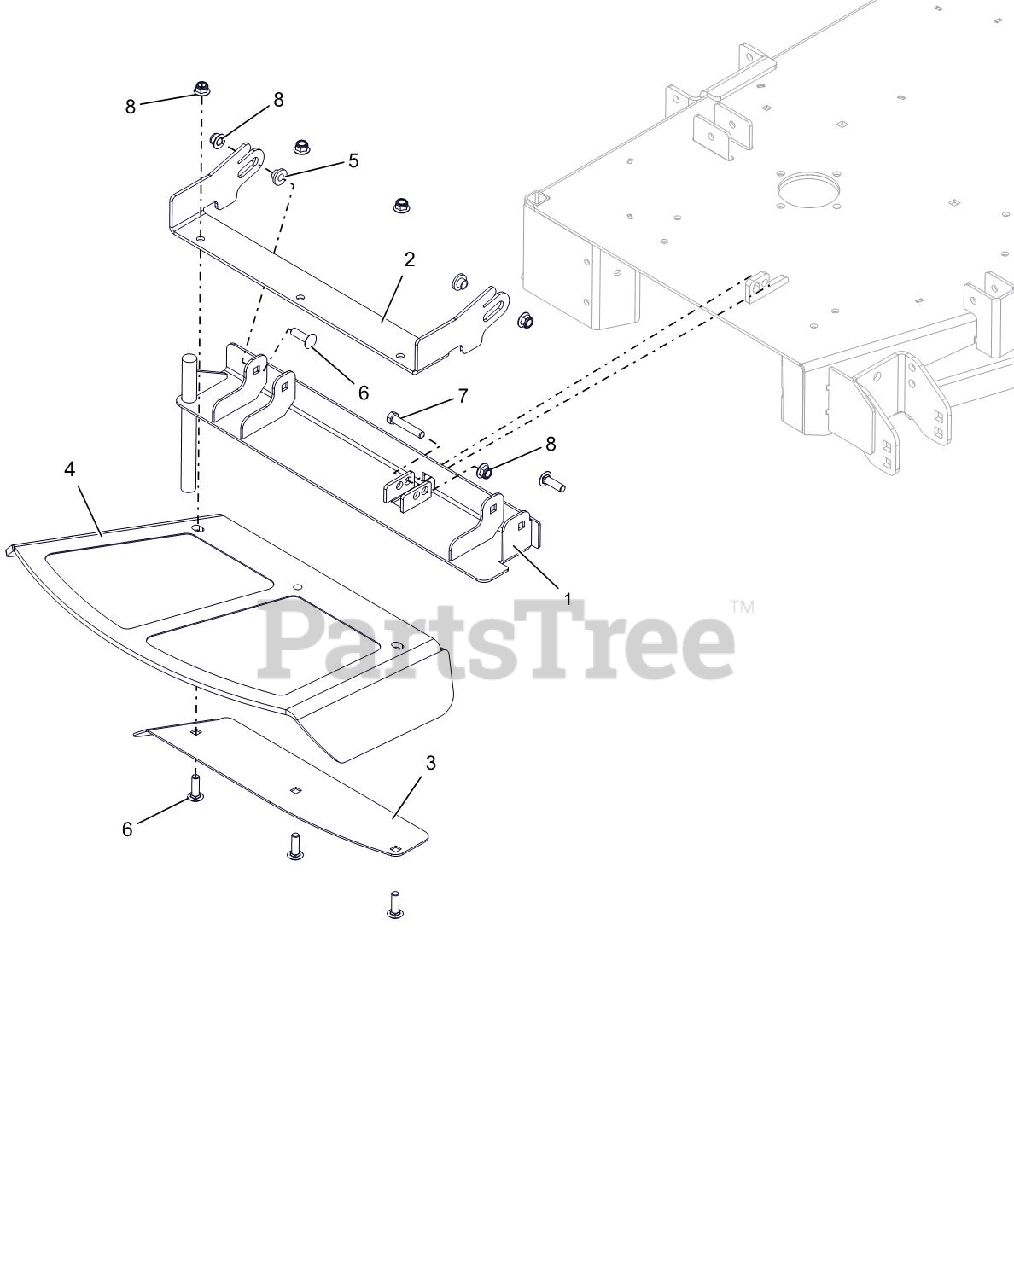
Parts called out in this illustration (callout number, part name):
1	48-60 DISCH CHT MTG WMT W/SAFE
2	48-60" CHUTE MTG BRKT - RED
3	48-60 DISCH CHUTE CLMP PLT-RED
4	CHUTE,48-60" FRMD RUBBER DISCH
5	BSHG-FLG .385X.500X.875X.406
6	@BLT-RHDSSQNK .38-16X1.25 G5YZ
7	@BLT-HEX .38-16X2.00 GR5 YWZC
8	@NUT-LK-NYL-FLG .38-16 YWZC
